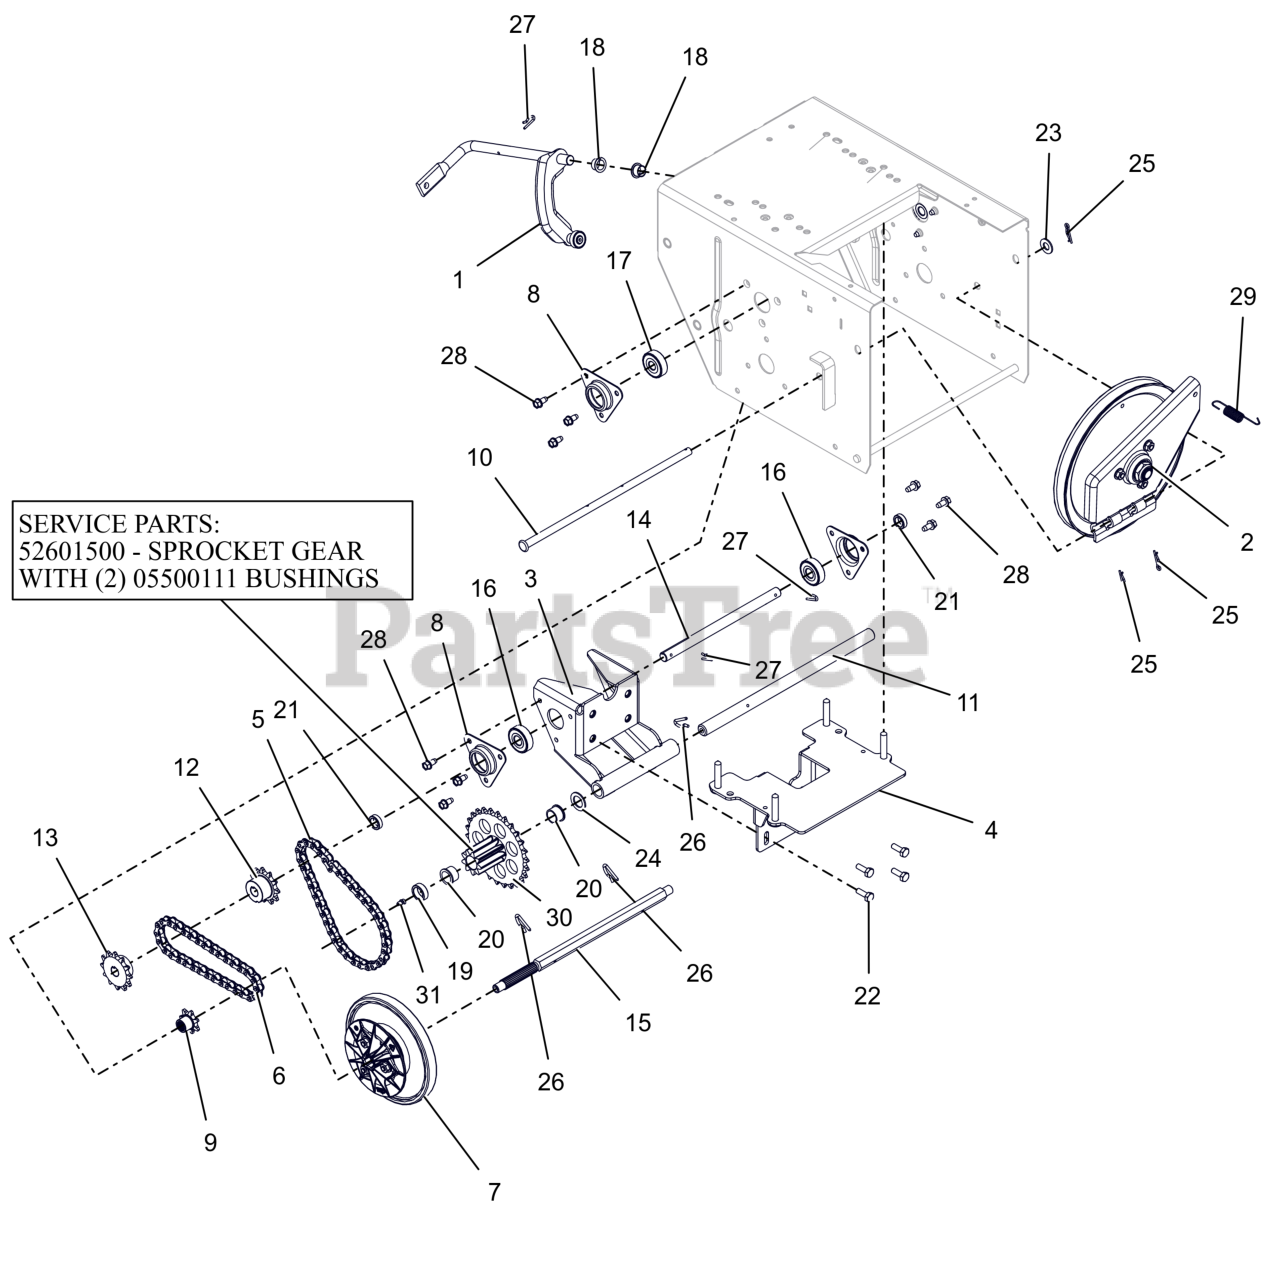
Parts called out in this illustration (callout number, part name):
1	ARM, SHIFT - ASSEMBLY
2	PLATE, SWING ASSEMBLY-DEEP
3	WLDMT, TRIPLE REDUCTION BRKT
4	STRAP, TRIPLE REDUCITON BOLT
5	CHAIN, ROLLER - #41X36 PITCHES
6	CHAIN - #41, 32 PITCHES
7	DISC, FRICTION DRIVE-ASSEMBLY
8	FLANGE, BEARING
9	SPROCKET, PINION 7T W/SPLINE
10	PIN, PIVOT
11	SHAFT, PINION-HARDENED
12	SPROCKET, 11 TOOTH
13	SPROCKET, 12 TOOTH
14	SHAFT, REDUCTION HEAT TREATED
15	SHAFT, HEX HEAT TREATED SPLINE
16	BRG-BALL .500X1.38X.437
17	BRG-BALL .437X1.375X.437
18	BUSHING, POLYLINER-.50 SPLIT
19	BSHG-SLV, .635X.880X.305
20	BSHG-FLG .625X.750X.500X.875
21	SPCR, SLV
22	BLT, HEX .25-20X.75 G5 ZCC
23	WSHR,FLT .406X.812X.065 ZCC
24	WSHR, FLT .630X1.005X.062 ZCC
25	PIN, HAIR #225 .072X1.09
26	PIN, SPRING CLIP
27	CLIP, SPRING
28	SCR-TAP .25-20X.50 HWH ZCC
29	SG-TENS .048X.50X2.8
30	PINION & SPROCKET
30	PINION & SPROCKET W/BUSHINGS
31	ZERK,FITTING .25X.125 DRIVE IN
